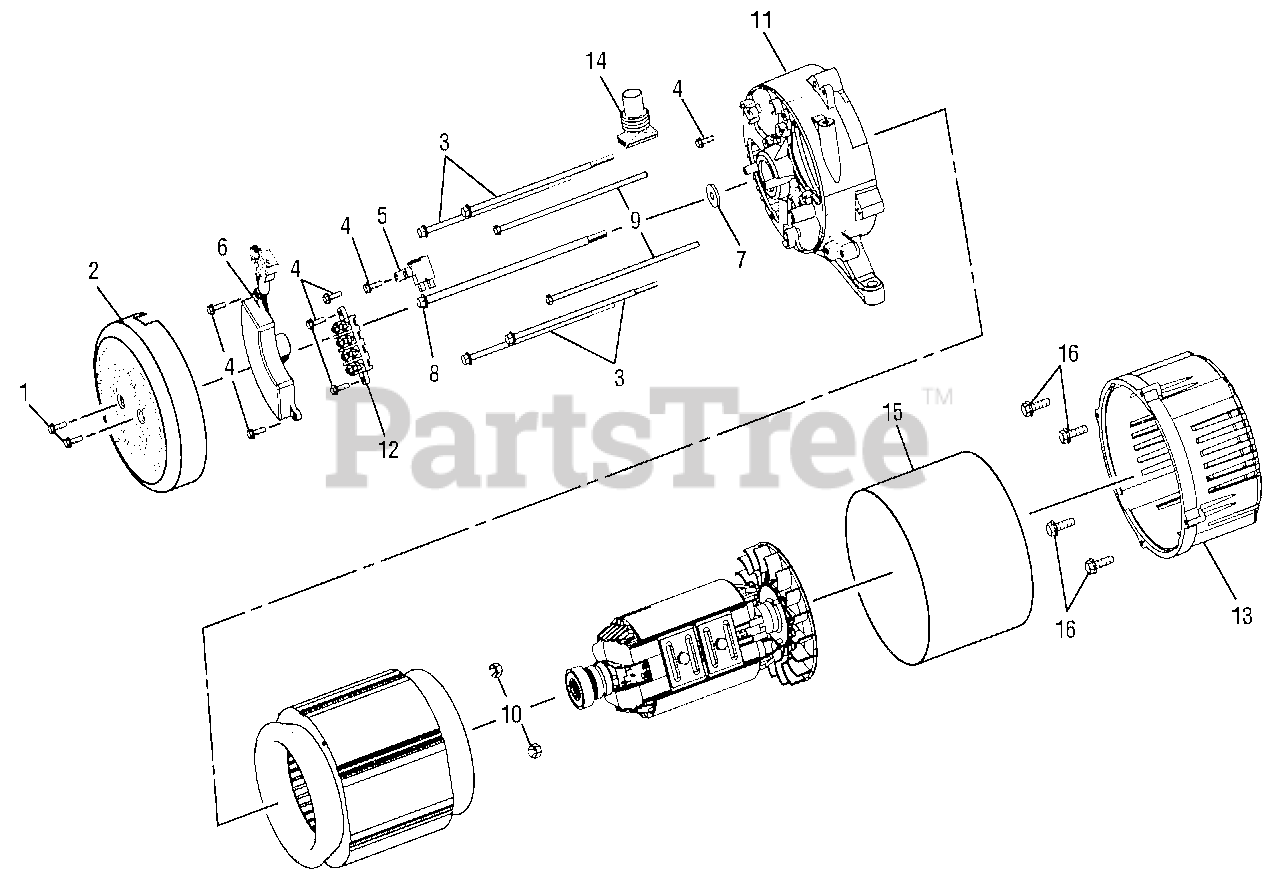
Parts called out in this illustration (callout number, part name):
1	Bolt (M5 x 10 mm, Flange Hex Hd.)
2	Brush Cover
3	Bolt (1/4-20 x 6 in., Hex Hd.)
4	Bolt (M5 x 16 mm, Flange Hex Hd.)
5	Brush Assembly
6	Automatic Voltage Regulator
7	Washer (5/16 in.)
8	Bolt (5/16-24 x 230 mm, Hex. Hd.)
9	Bolt (M5 x 230 mm, Hex. Hd)
10	Hex Nut (M5)
11	Bearing Support
12	Terminal Block
13	Engine Adapter
14	Rubber Boot
16	Bolt (3/8-16 x 1-1/4 in.)
